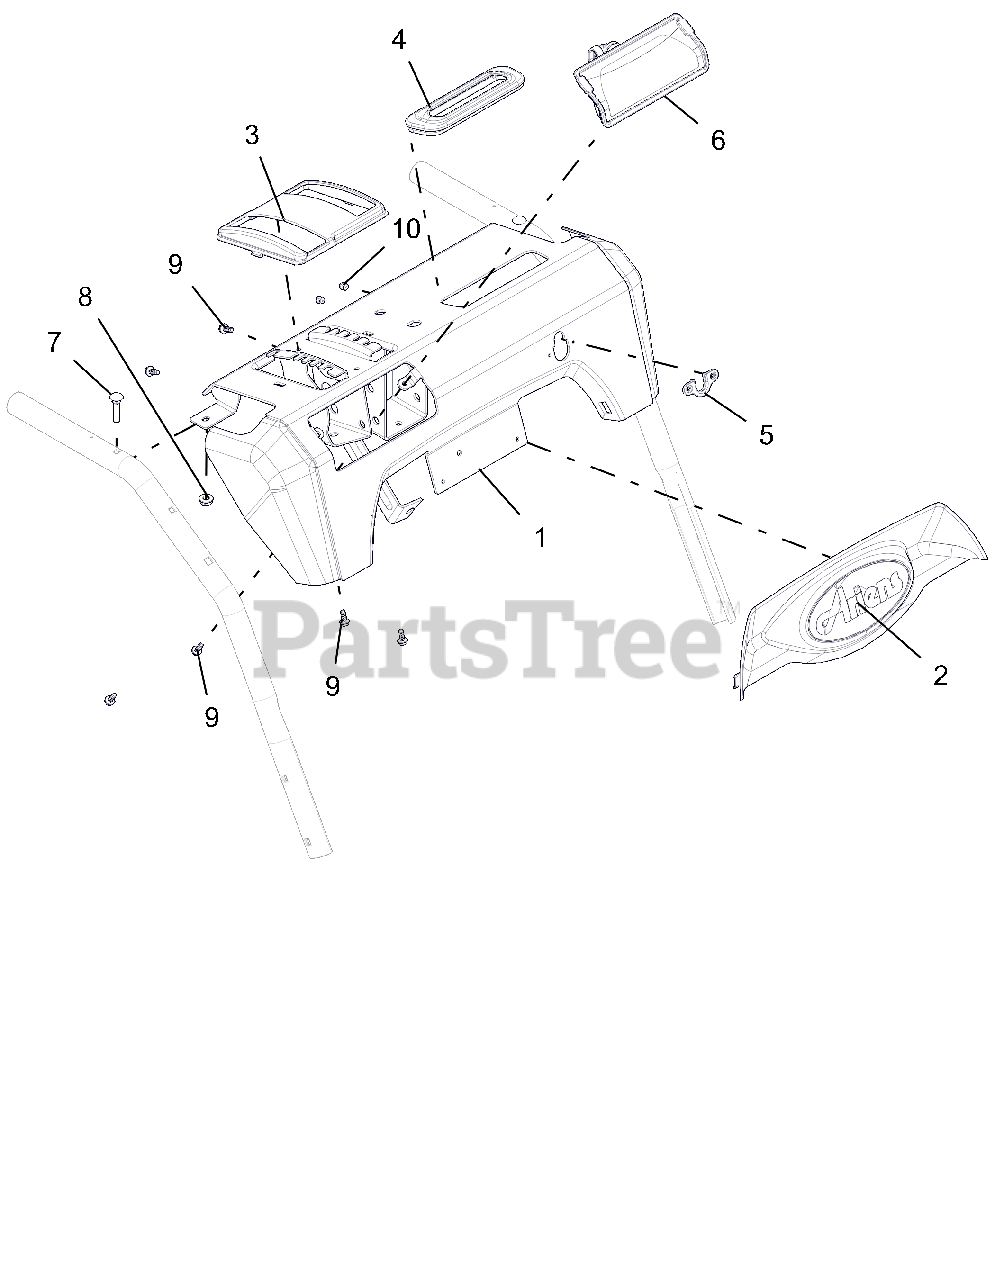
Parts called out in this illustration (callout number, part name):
1	CONTROL PANEL W/DECAL QT2
2	DASH BEZEL, ARIENS LOGO - PRO
3	BEZEL, SHIFT
4	GROMMET, BOOT, QUICK TURN
5	GROMMET, CABLE, QUICK TURN 2
6	HEADLIGHT ASY, HALO 20W 2SHOT
7	BLT-RDHDXLSQNK.25-20X1.25 G5ZC
8	@NUT-LK-CTR-FLG .25-20 YWZC
9	SCR-TAP #10X.50 BOSS INDHXHD
10	RVT-POP #43 .125X.313 STL ZINC
